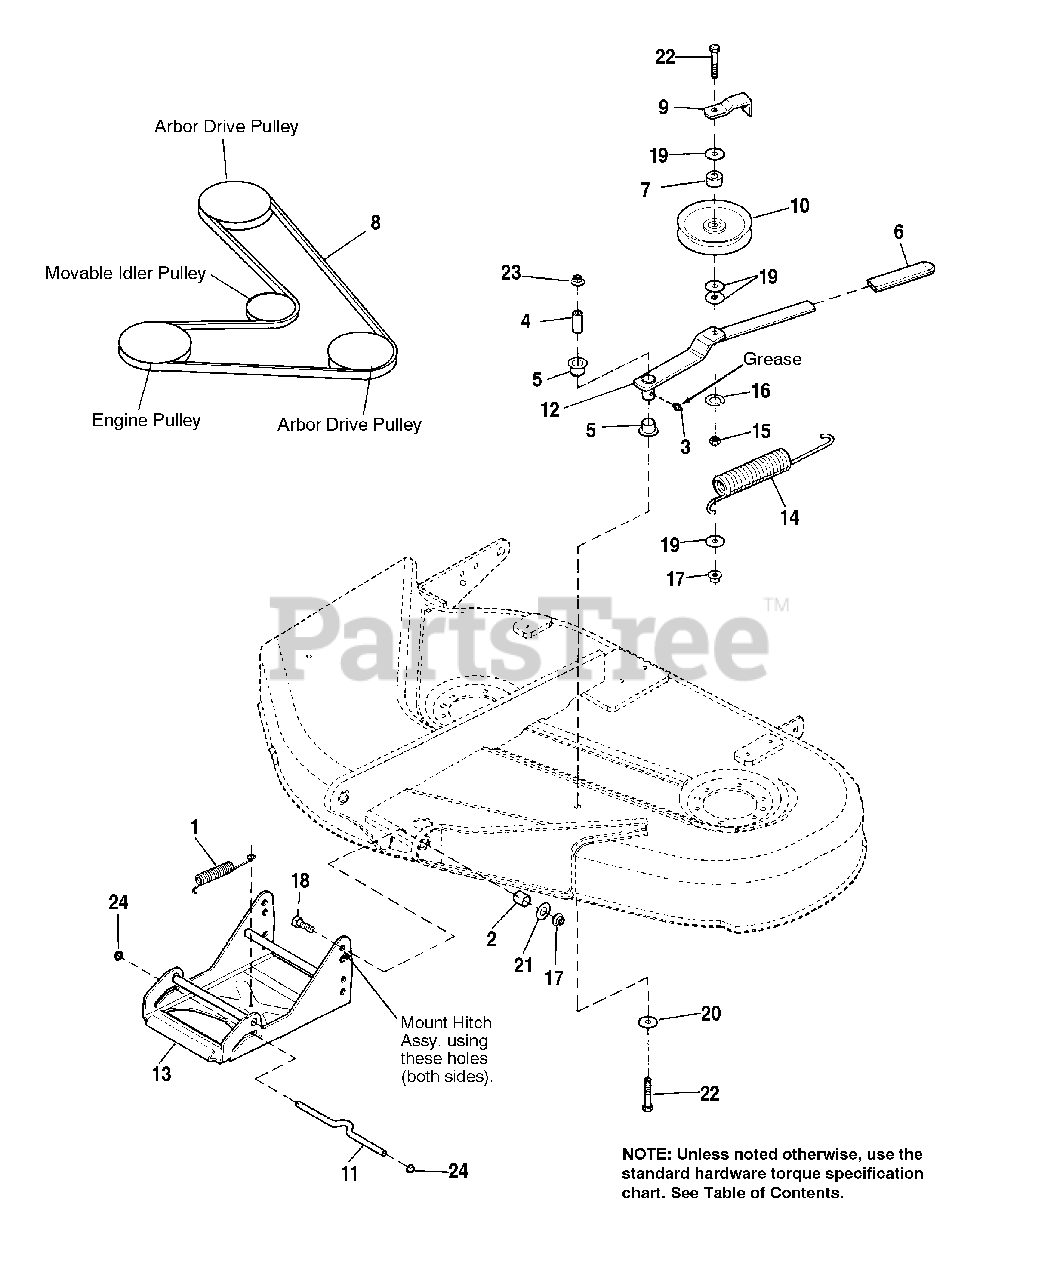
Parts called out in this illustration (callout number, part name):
3	FITTING, Grease
6	GRIP, Lever
9	GUARD, Belt
10	IDLER PULLEY
12	CLUTCH LEVER ASSY.
13	HITCH ASSY.
15	NUT, Hex, Full, 3/8-16
16	LOCKWASHER, 3/8
17	NUT, Hex, Lock, 3/8-16
18	CAPSCREW, Hex, 3/8-16 x 1-1/2
19	WASHER, Plain
20	WASHER
21	WASHER, Plain, 3/8 I.D.
22	CAPSCREW, Hex Hd., 3/8-16 x 2-3/4
23	NUT, Hex, Flange, 2-Way Lock, 3/8-16
24	NUT, Push On, 3/8
